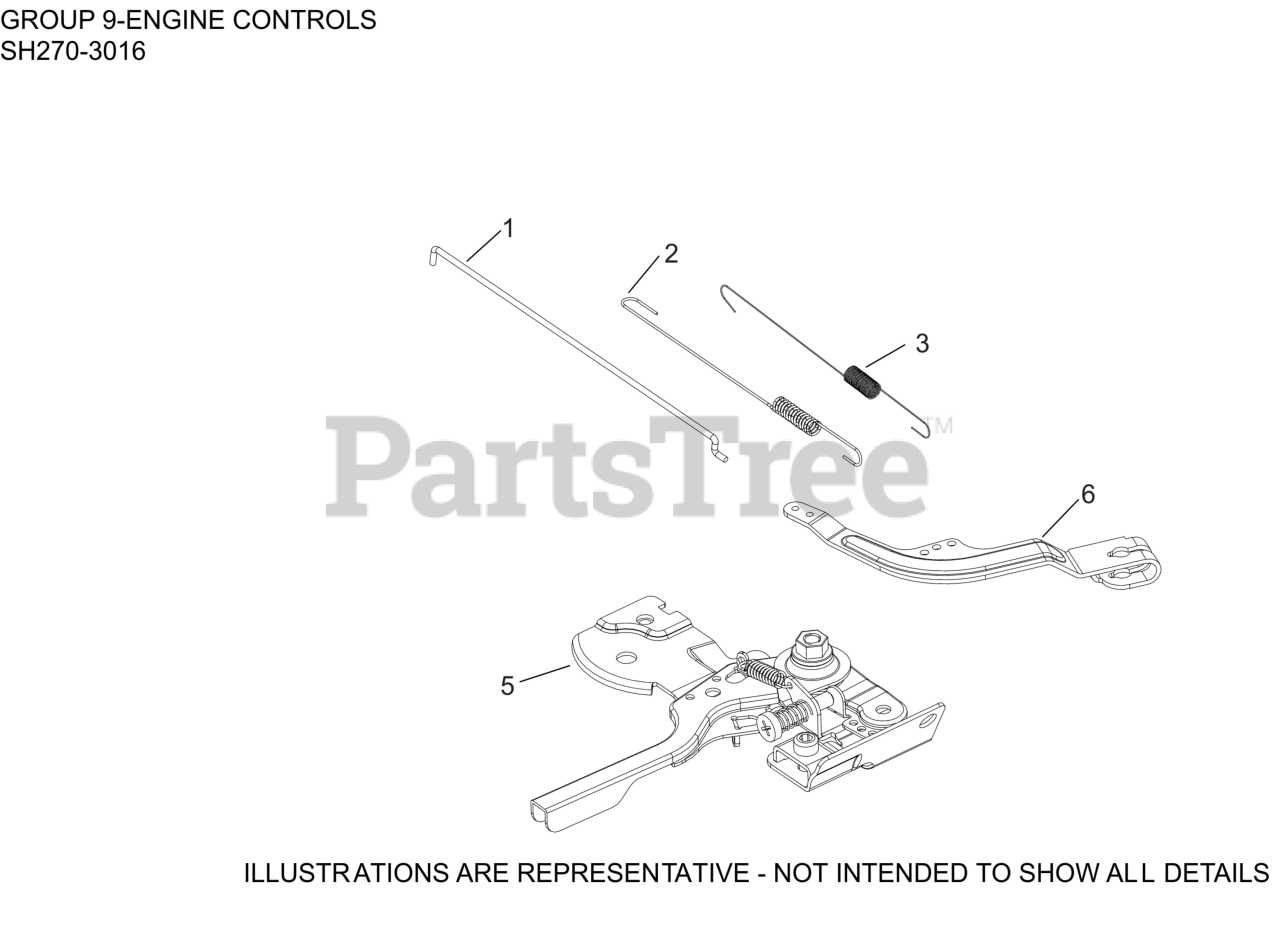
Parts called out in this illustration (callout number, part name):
1	LINKAGE, GOVERNOR-USE 18 079 05-S
2	SPRING, GOVERNOR
3	SPRING, LINKAGE
5	SPEED CONTROL ASSEMBLY-FIXED
6	KIT, GOVERNOR LEVER
